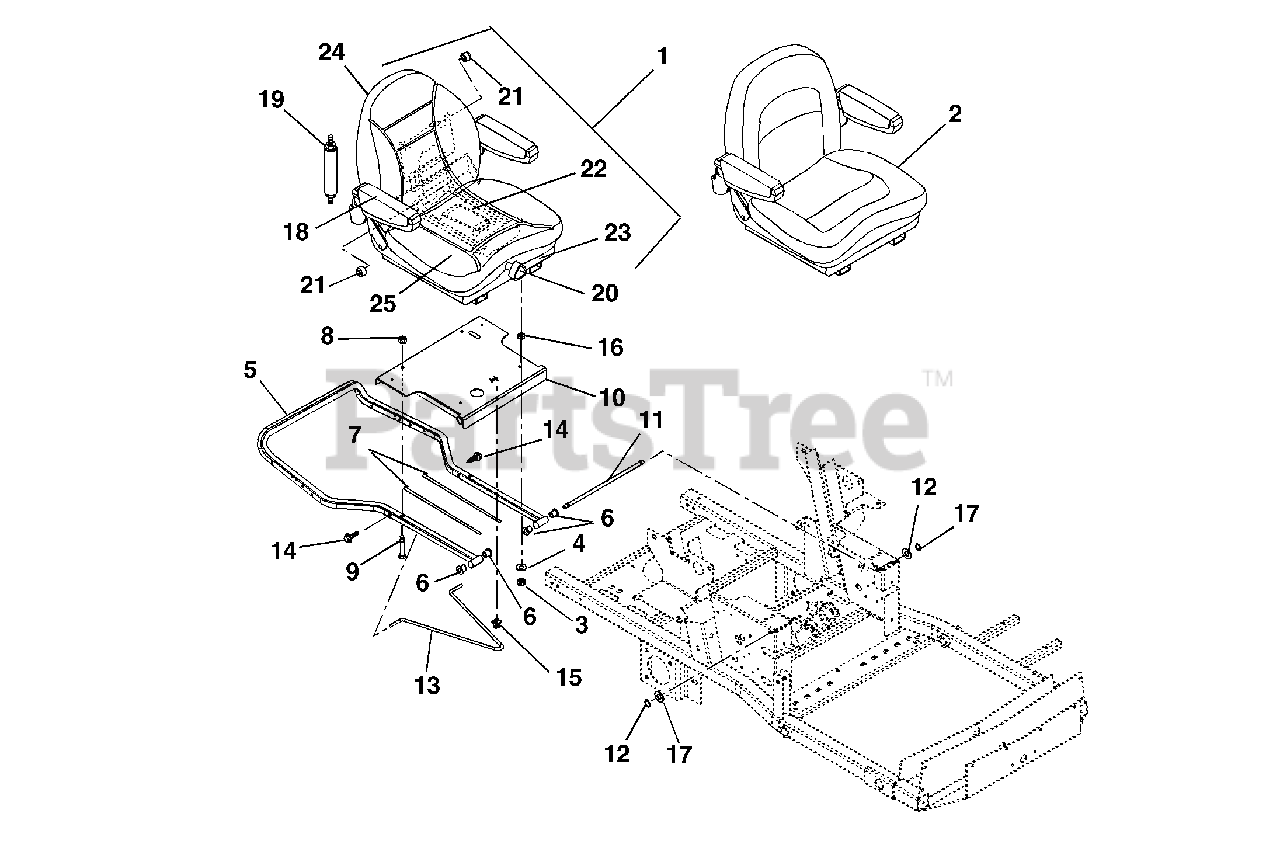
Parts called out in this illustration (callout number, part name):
1	Seat-Suspension
2	Seat- Suspension
3	Nut-Locking-Nylon M8-1.25
3	Nut-Locking-Nylon .312-18
4	Washer-Flat-Steel .38 x .875 x .083
5	Weldment- Hood Frame
5	Weldment - Seat Frame
6	Bushing-Flange .515 x .750 x .745 x 1.00
7	Tape -VHB 4941F
8	Nut-Locking-Top-Flange .38-16
9	Bolt-Rib Neck .38-16 x 1.50
10	Weldment-Seat Pivot Plate
11	Rod-Seat Frame Pivot
12	Ring-Retaining-External .500 x .050
13	Rod-Prop
14	Screw-Tapping .25-20 x .50 Hex Washer Head
15	Clip
16	Bushing-Sleeve .377 x .624 x .235
17	Washer-Flat-Steel .531 x 1.06 x .095
18	Kit-Arm Pad (1 per bag)
19	Kit-Damper w/Hardware
20	Kit-Knob (1 per bag)
21	Kit-Roller (4 per bag)
22	Kit-Spring Cable (1 per bag)
23	Kit-Adjuster (1 per carton)
24	Kit-Seatback
25	Kit-Cushion (1 per carton)
